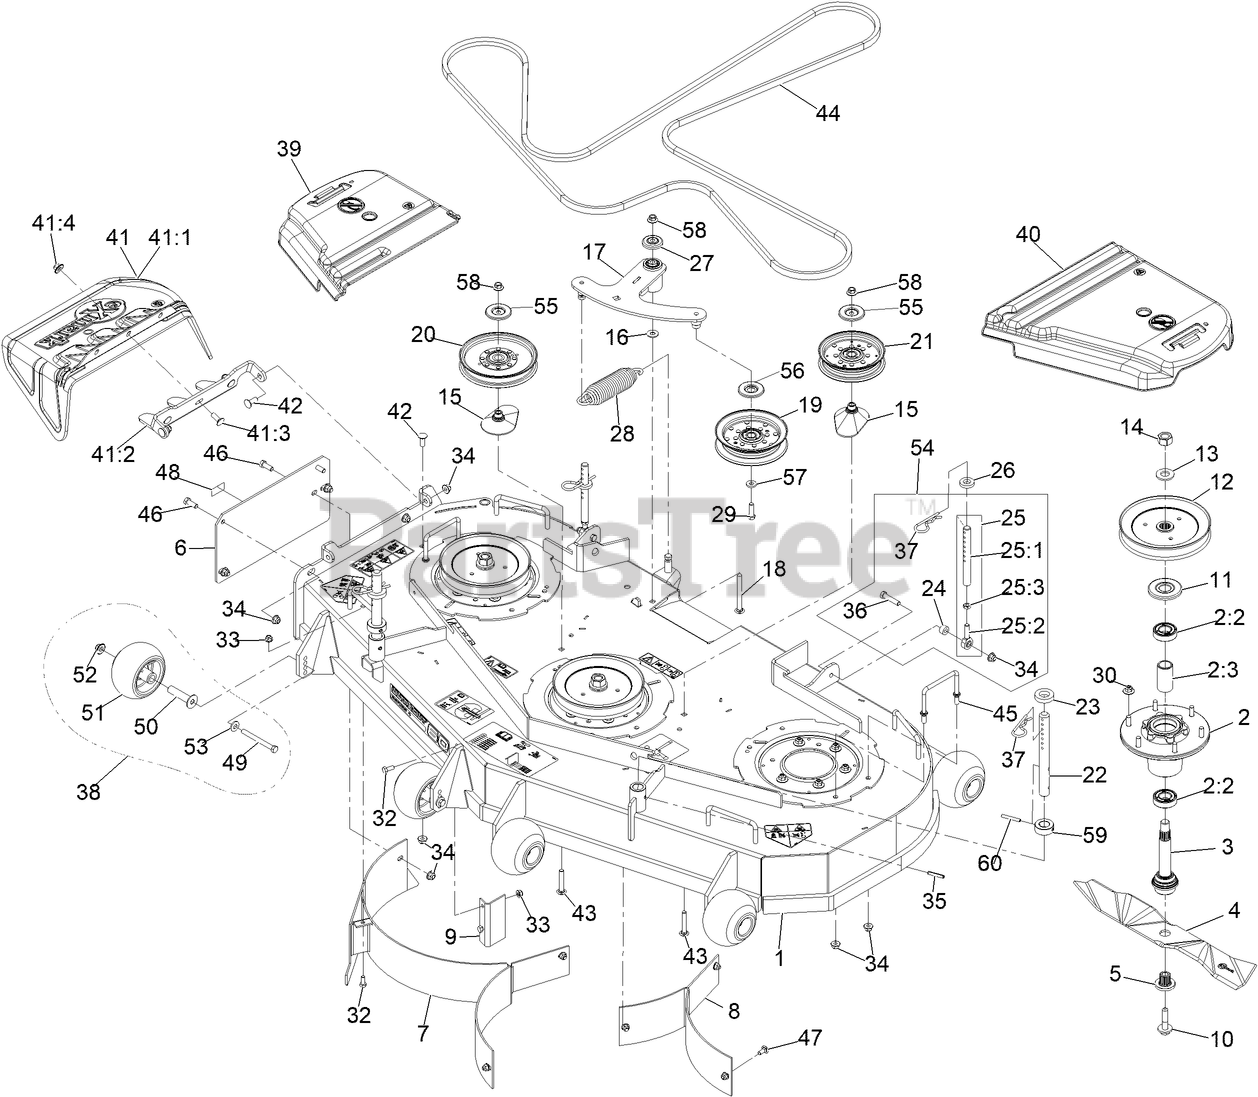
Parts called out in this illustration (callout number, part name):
1	ASM, DECK W/ DECALS, 60
2	ASM-CUTTER HSG WITH BEARINGS
2:2	BEARING-BALL
2:3	SPACER-BEARING
3	ASM-SPINDLE AND SEAL
4	Blade-Extreme 2, 20.50"
5	BUSHING,SPLINED
6	XREF 1-633957-01 (EXMARK)
7	BAFFLE WLD RH MULCH
8	BAFFLE WLD LH MULCH
9	XREF 1-633956-03 (EXMARK)
10	SCREW,SEMS 1/2-20 X 2.19
11	GUARD,BEARING TOP .989
12	SHEAVE,BLADE DRIVE 7.25
14	NUT-HEX
15	SPACER-PULLEY
16	WASHER-FLAT
17	ASM, DECK IDLER
18	SCREW-CARR
19	IDLER-PULLEY, FLAT
20	IDLER-PULLEY
21	PULLEY-IDLER, FLAT
22	ROD, DECK SUPPORT
23	SPACER-DECK SUPPORT
25:1	LINK,SUPPORT
25:2	BALLJOINT
25:3	NUT-HJ
27	GUARD-TOP
28	SPRING-EXTENSION
29	SCREW-HH
30	Nut-Nyloc 3/8-16 Flg
32	SCREW-HH
33	NUT-HF, NI
34	NUT-HF, NI
36	SCREW-HH
37	PIN,HAIR COTTER
38	KIT, ANTI-SCALP ROLLER
39	COVER-BELT, RH
40	COVER-BELT, LH
41	ASM,DISCHARGE CHUTE
41:1	CHUTE,DISCHARGE
41:2	BRACKET,DISCHARGE CHUTE
41:3	SCREW-CARR
41:4	Nut-Nyloc 3/8-16 Flg
42	SCREW-CARR
43	BOLT-CARR, SHORT NECK
45	WIREFORM-COVER
46	SCREW-HH
47	BOLT-CARR
48	Decal-Patent Ttco.Com
49	SCREW-HH 3/8-16 X 3 3/4 GR 8
50	AXLE, ROLLER
51	ROLLER-SCALP, ANTI
52	Nut-Nyloc 3/8-16 Flg
53	WASHER-BELLEVILLE
54	KIT,SUPPORT LINK W/PIN
55	SHIELD-DUST
56	SHIELD-GUARD, DUST
59	COLLAR, DECK HEIGHT PIN
60	PIN-ROLL
